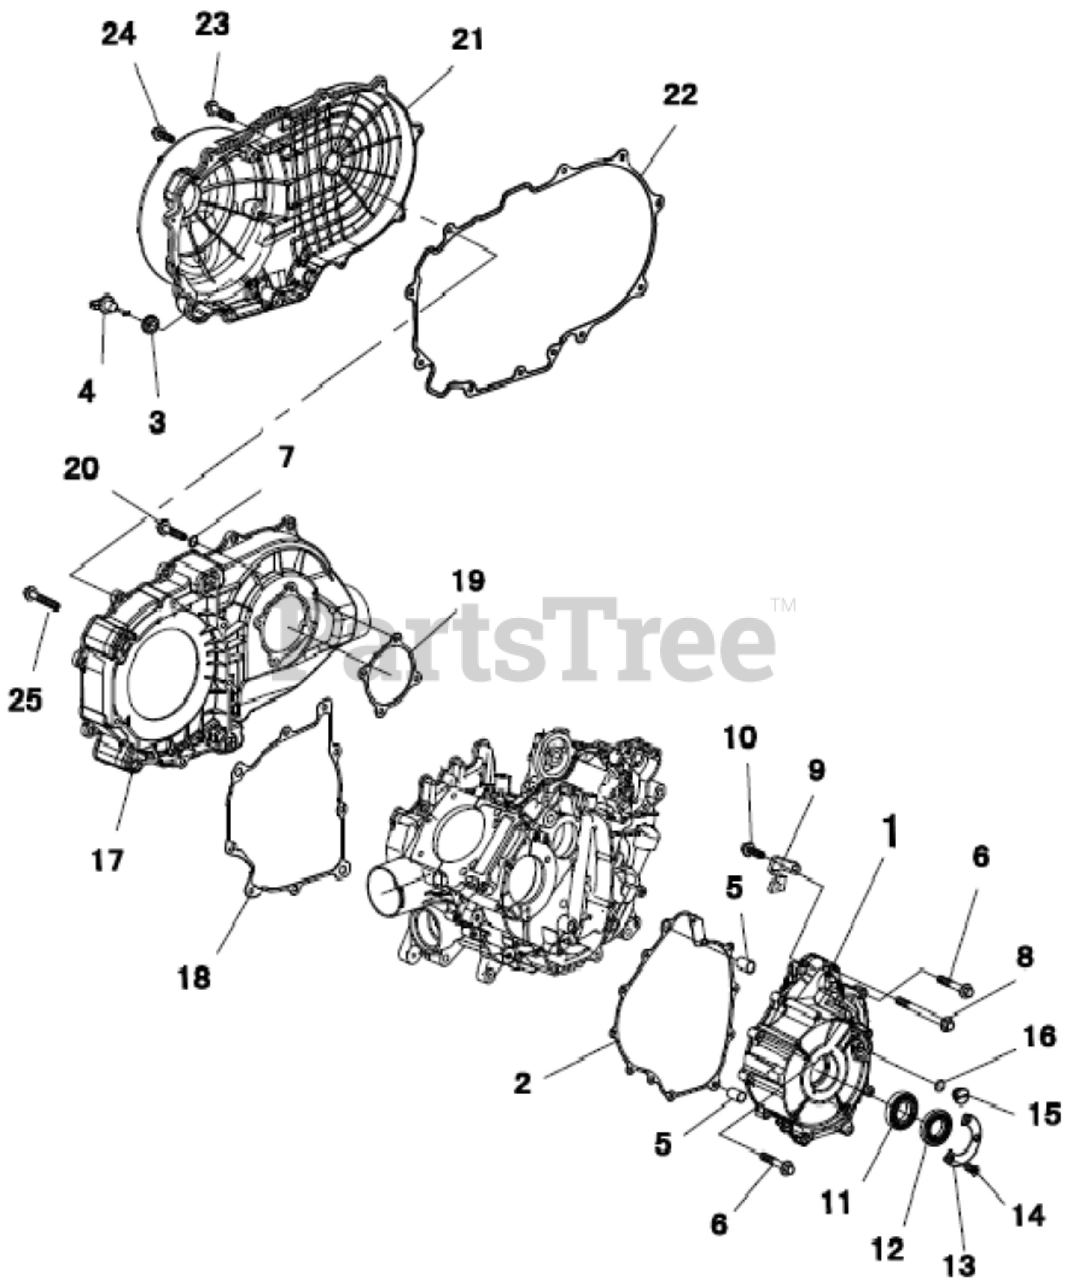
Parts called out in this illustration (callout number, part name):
1	Left Crankcase Cover
2	Gasket,Left Crankcase Cover
4	Plug,Clutch Cover
5	Pin,Dowel 10x16
6	Hex flange bolts M6x30
7	Spring Washer 6
8	Hex flange bolts M6x40
9	Stator wire guard plate
10	Hex flange bolts M6x12
11	Bearing 60/28
12	Oil Seal 28x52x8.5
13	Press Plate,Oil Seal
14	Cross recessed countersunk head screw M5x12
15	Small Peep Hole Cover
16	O-Ring 13.4x2.35
17	Cover,Clutch,Inner
18	Seal,Clutch Inner Cover I
19	Seal,Clutch Inner Cover II
20	Hex flange bolts M6x32
21	Cover,Clutch,Outer
22	Seal,Clutch Cover
23	Hex flange bolts M6x25
24	Hex flange bolts M6x16
25	Hex flange bolts M6x50
